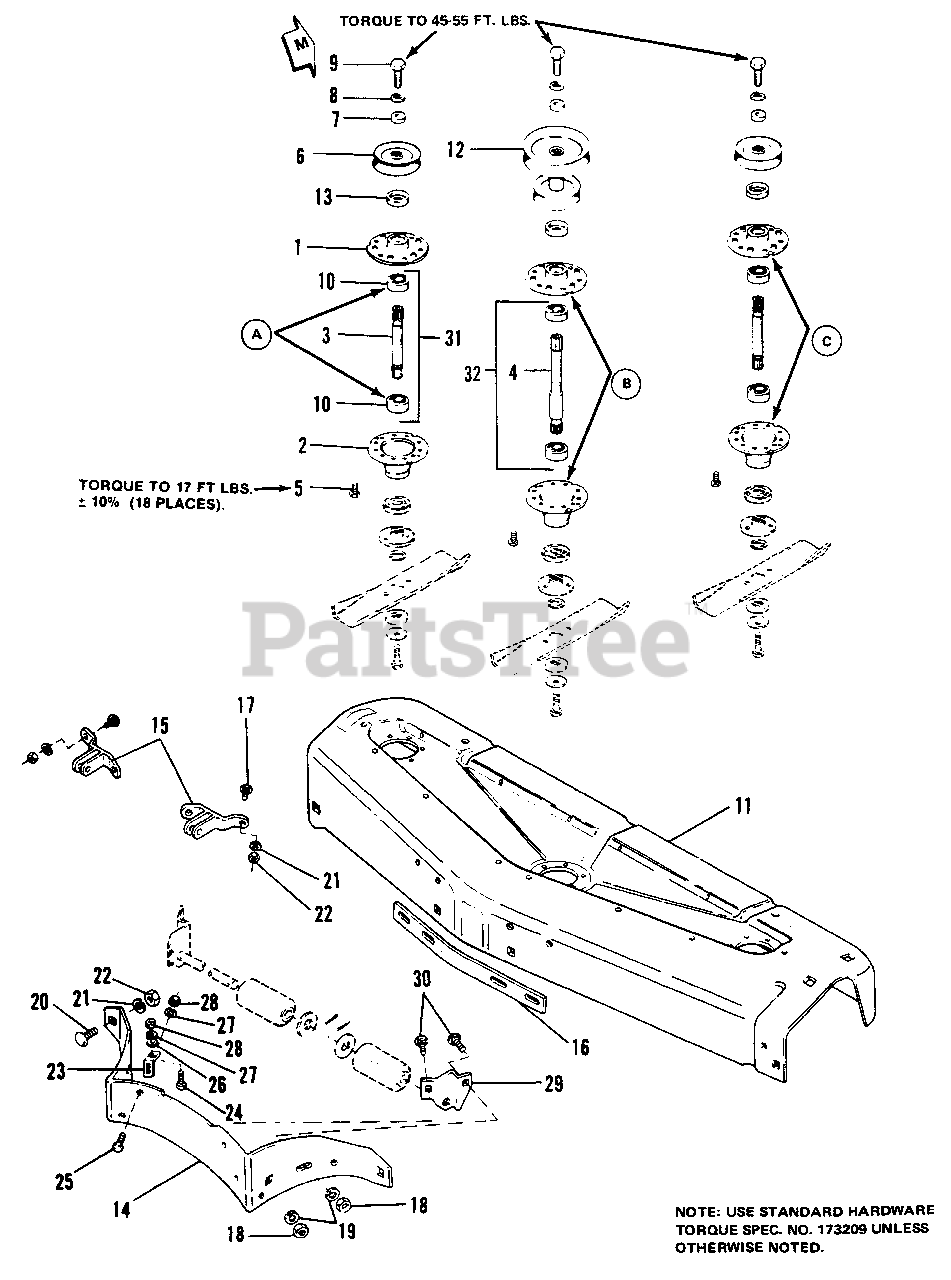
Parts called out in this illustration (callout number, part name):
1	HOUSING, Top
2	HOUSING, Bottom
3	SHAFT, Arbor
4	SHAFT, Arbor, Center
5	SCREW, Hex Wshr. Hd., 5/16 x 5/8
6	PULLEY ASSY, Deck Drive
7	WASHER
8	LOCKWASHER, 7/16
9	CAPSCREW, Hex Hd., 7/16-14 x 1-1/4
11	HOUSING, 48"
12	PULLEY ASSY
13	SHIELD, Bearing Upper, Arbor
15	BRACKET ASSY, Front
16	BAR, Reinforcement
17	BOLT, Carriage, 3/8-16 x 1
18	NUT, Hex, Full, 5/16-18
19	LOCKWASHER, 5/16
20	BOLT, Carriage, 3/8-16 x 3/4
21	LOCKWASHER, 3/8
22	NUT, Hex, Full, 3/8-16
23	CLIP, Baffle
24	SCREW, Thd. Forming, 1/4-20 x 7/8
25	CAPSCREW, Hex Hd., 1/4-20 x 5/8
26	WASHER, Plain, 1/4
27	LOCKWASHER, 1/4
28	NUT, Hex, Full, 1/4-20
29	BRACKET, Roller, L.H.
30	BOLT, Carriage, 5/16-18 x 3/4
31	SHAFT & BEARING ASSY
32	SHAFT & BEARING ASSY, Center
